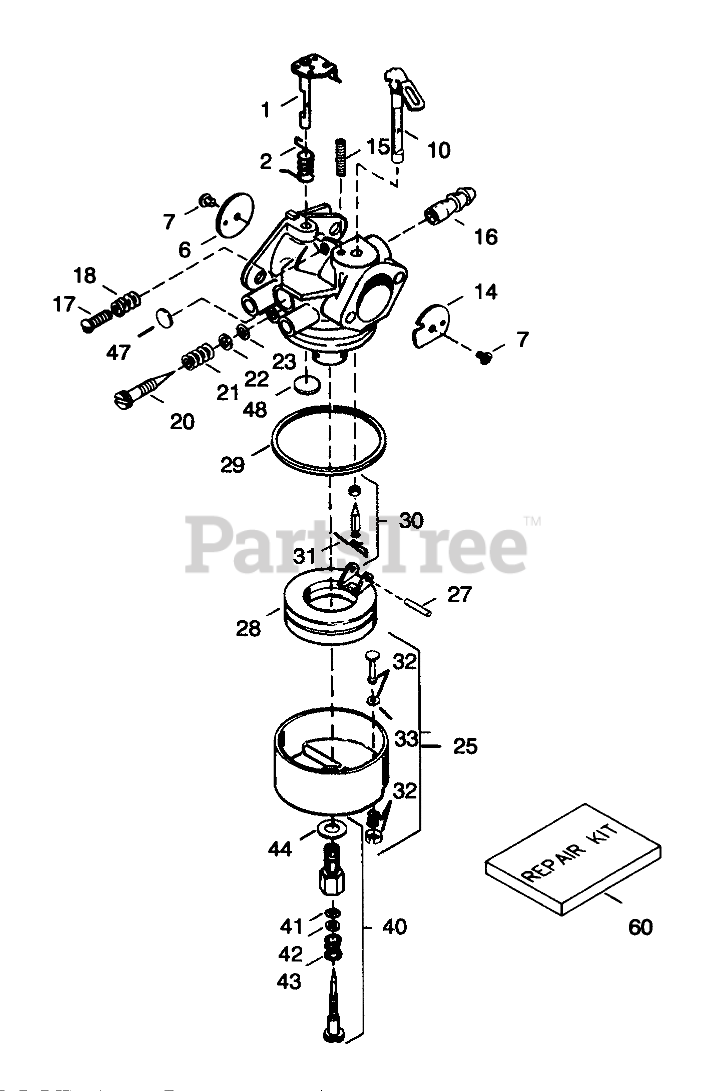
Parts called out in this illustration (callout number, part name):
1	Throttle Shaft and Lever ASM
2	Spring-Return, Throttle
6	Shutter-Throttle
7	Screw-Shutter
10	Choke Shaft and Lever ASM
14	Shutter-Choke
15	Spring-Positioning, Choke
16	Fitting-Fuel
17	Screw-Throttle Crack Screw / Idle Speed
21	Spring-Tension
23	"O"Ring
24	Screw-Idle Mix
25	Float Bowl Assembly (Incl. Ref. #32 & 33)
27	Shaft-Float
28	Float
29	O Ring-Bowl, Float
30	Inlet Needle, Seat & Clip Assy. (Incl. Ref. #31)
31	Clip-Spring
32	Drain Assembly (Incl. Ref. #33)
33	Gasket-Plunger, Drain
40	Adjustment Screw Assy. (Incl. Ref. #43, 44, 41 &42)
41	"O"Ring
44	Washer-Bowl Nut
47	Plug-Welch, Idle Mixture Well
48	Plug-Welch, Atmospheric Vent
60	Kit-Repair
